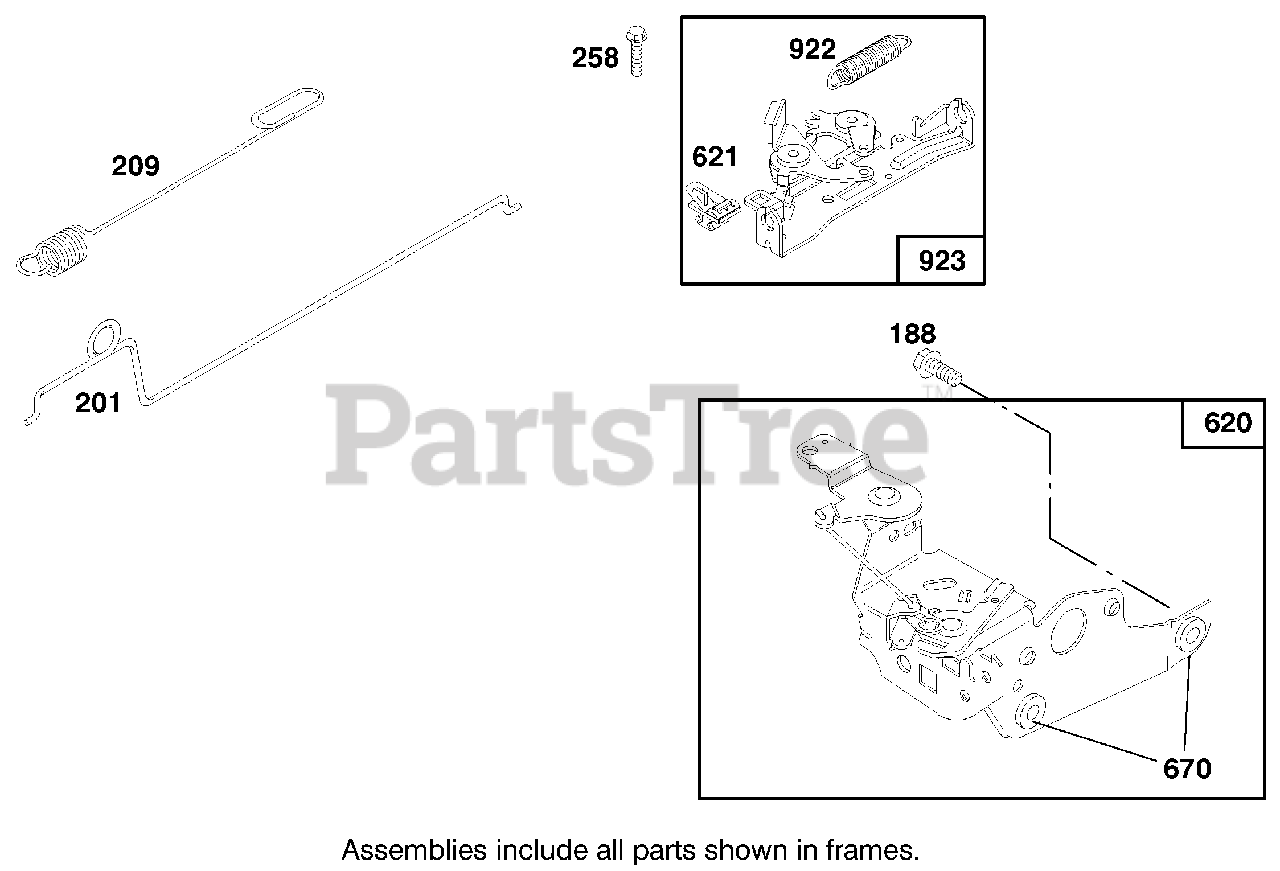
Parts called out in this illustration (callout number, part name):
188	Screw-Hex. Head
201	Link-Governor
209	Spring-Governor
258	Screw-Hex. Head
620	Bracket-Carburetor
621	Switch-Stop
670	Spacer-Bracket
922	Spring-Brake
923	Brake Assembly
